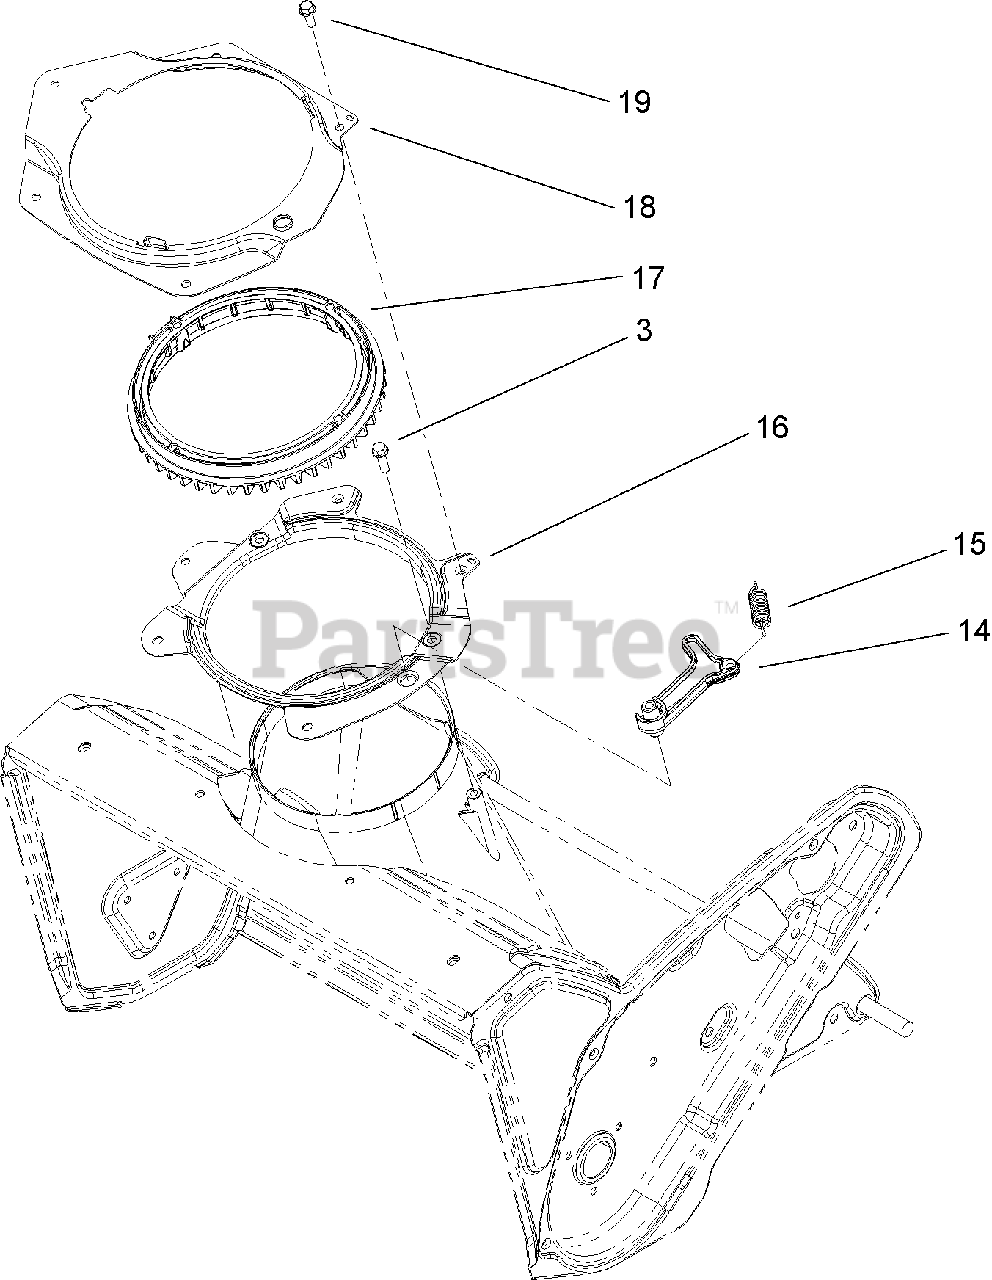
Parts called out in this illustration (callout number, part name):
3	SCREW-HWH
14	PAWL-DETENT
15	SPRING-EXTENSION
16	RING-SUPPORT, CHUTE
17	RING-CHUTE, DETENT
18	RETAINER-RING, CHUTE
19	SCREW-HWH
